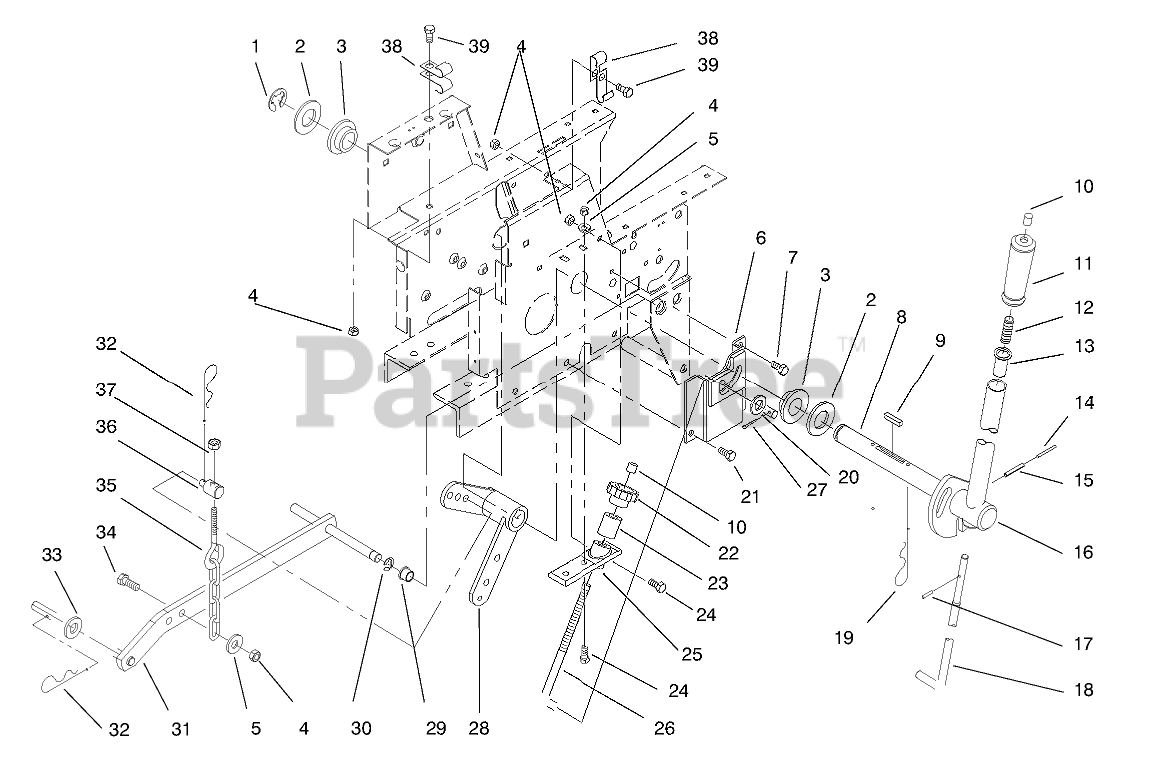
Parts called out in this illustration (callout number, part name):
1	RING-RETAINING
2	WASHER-FLAT
3	BEARING-FLANGE
4	NUT-LOCK, NI
5	WASHER-PLAIN
6	LIFT LEVER ASM
7	Bolt
8	SHAFT-LIFT LEVER
9	KEY-SQUARE
10	CAP-ROD, PLUNGER
11	GRIP-HANDLE
12	SPRING-COMPRESSION
13	RETAINER-SPRING
14	PIN-SPRING
15	PIN-ROLL
16	LIFT HANDLE ASM
17	PIN-SPIROL
18	ROD-LATCH LIFT
19	PIN-HAIR
20	WASHER-FLAT
21	SCREW-SELF TAP
22	KNOB-LIFT CONTROL
23	SLEV-LIFT ADJS
24	SCREW-HH
25	CASTING-LIFT LEVER
26	ROD-HEIGHT CONTROL
27	PIN-COTTER
28	LIFT LEVER ASM
29	BUSHING
30	RING-RETAINING, EXTERNAL
31	Bar-Lift
32	PIN-HAIR
33	WASHER-FLAT
34	SCREW-HH
35	CHAIN-LIFT
36	TRUNNION-LIFT
37	NUT-LOCK, NI
38	CLIP
39	SCREW-HH
